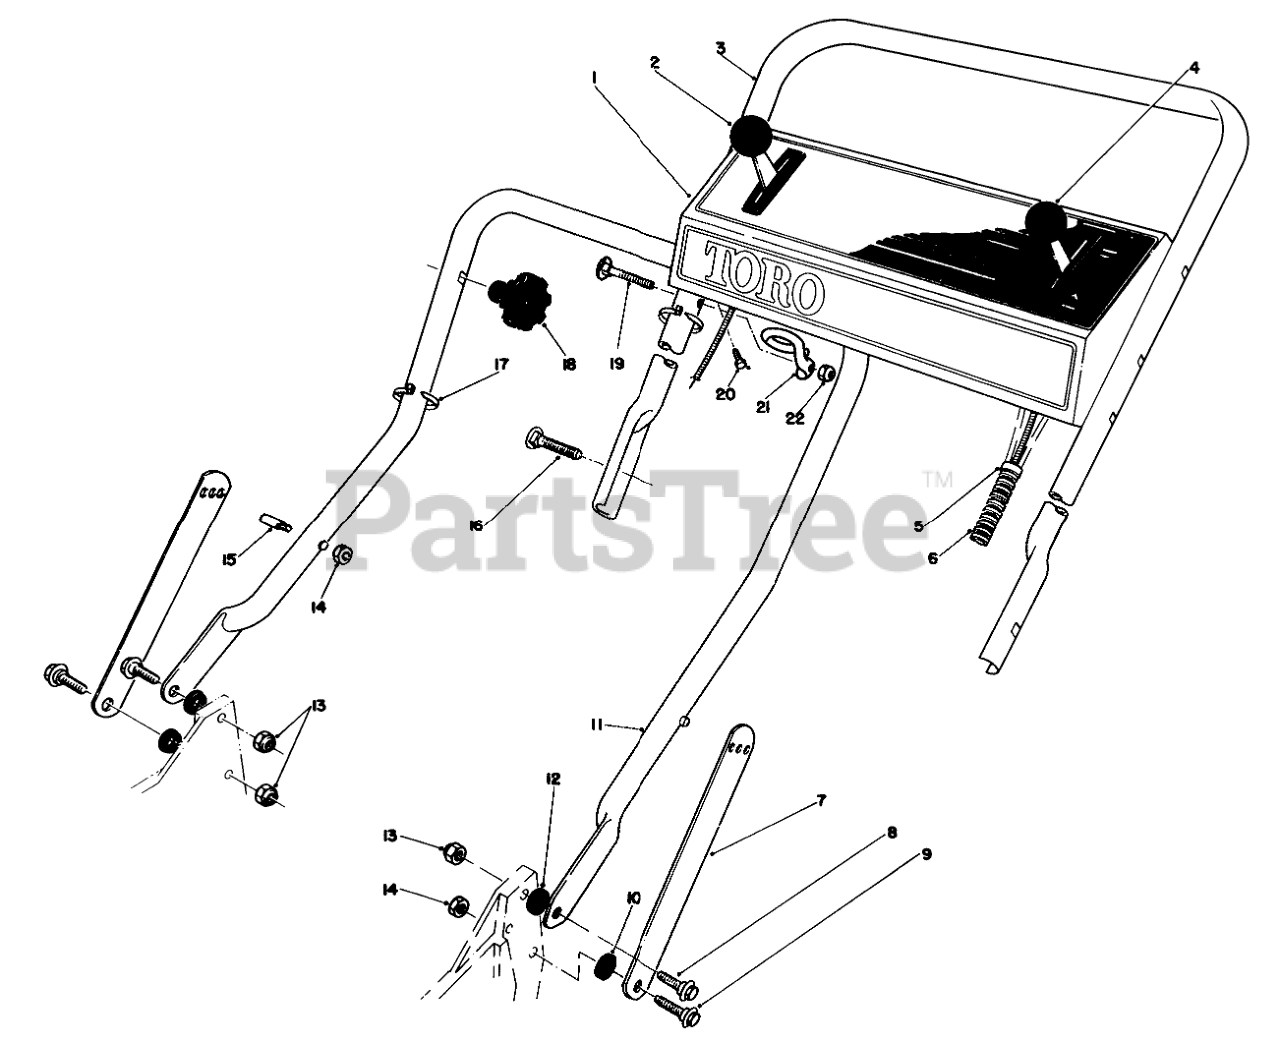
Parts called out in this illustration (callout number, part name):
1	Panel-Control
2	GROUND SPEED CONTROL
3	UPPER HANDLE
4	SERVICE THROTTLE CONTRO
5	FITTING-RING
6	CONTROL CABLE COVER
7	Handle Latch
8	SCREW-SHOULDER
9	SCREW-SHOULDER
10	SPACER
11	LOWER HANDLE ASM
12	SPACER
13	NUT-LOCK, NI
14	NUT-LOCK, NI
15	HANDLE PIN
16	5/16-18 X 2 HNDLE SCREW
17	TIE-CABLE
19	HANDLE SCREW
20	SCREW-HWHTF
21	Guide
22	NUT-LOCK, NI
